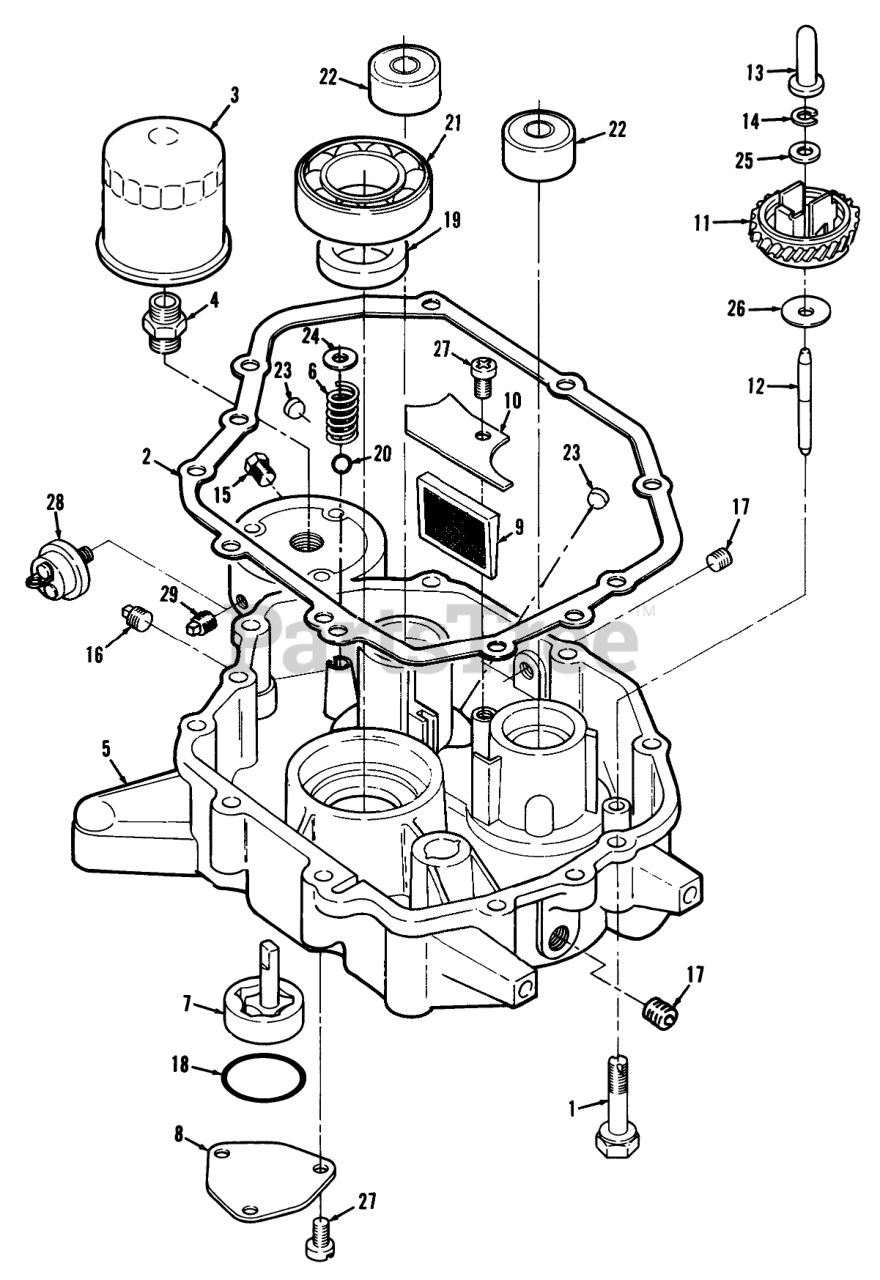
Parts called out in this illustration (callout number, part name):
1	SELF-TAP BOLT SP M8
2	Gasket
3	FILTER
4	ADAPTER
5	BASE-0IL
6	SPRING
7	PUMP-OIL
8	COVER-OIL PUMP
9	SCREEN
10	COVER
11	GEAR-GOVERNOR
12	SHAFT-GOVERNOR
13	Sleeve
14	STOP-GOVERNOR
15	PLUG-HEX HD
16	PLUG - SQUARE HEAD
18	RING-O
19	SEAL-OIL CRNKSHFT UP
20	BALL-BEARING
21	BRNG-BALL CRANKSH L
22	BRNG-BALL BAL SHFT L
23	PLUG-CORE HOLE
24	RETAINING-RING
25	WASHER-1.6MM THK
26	WASHER-1MM THK
27	SCREW-M6 X 14
28	SWITCH-OIL PRESSURE
29	Plug
